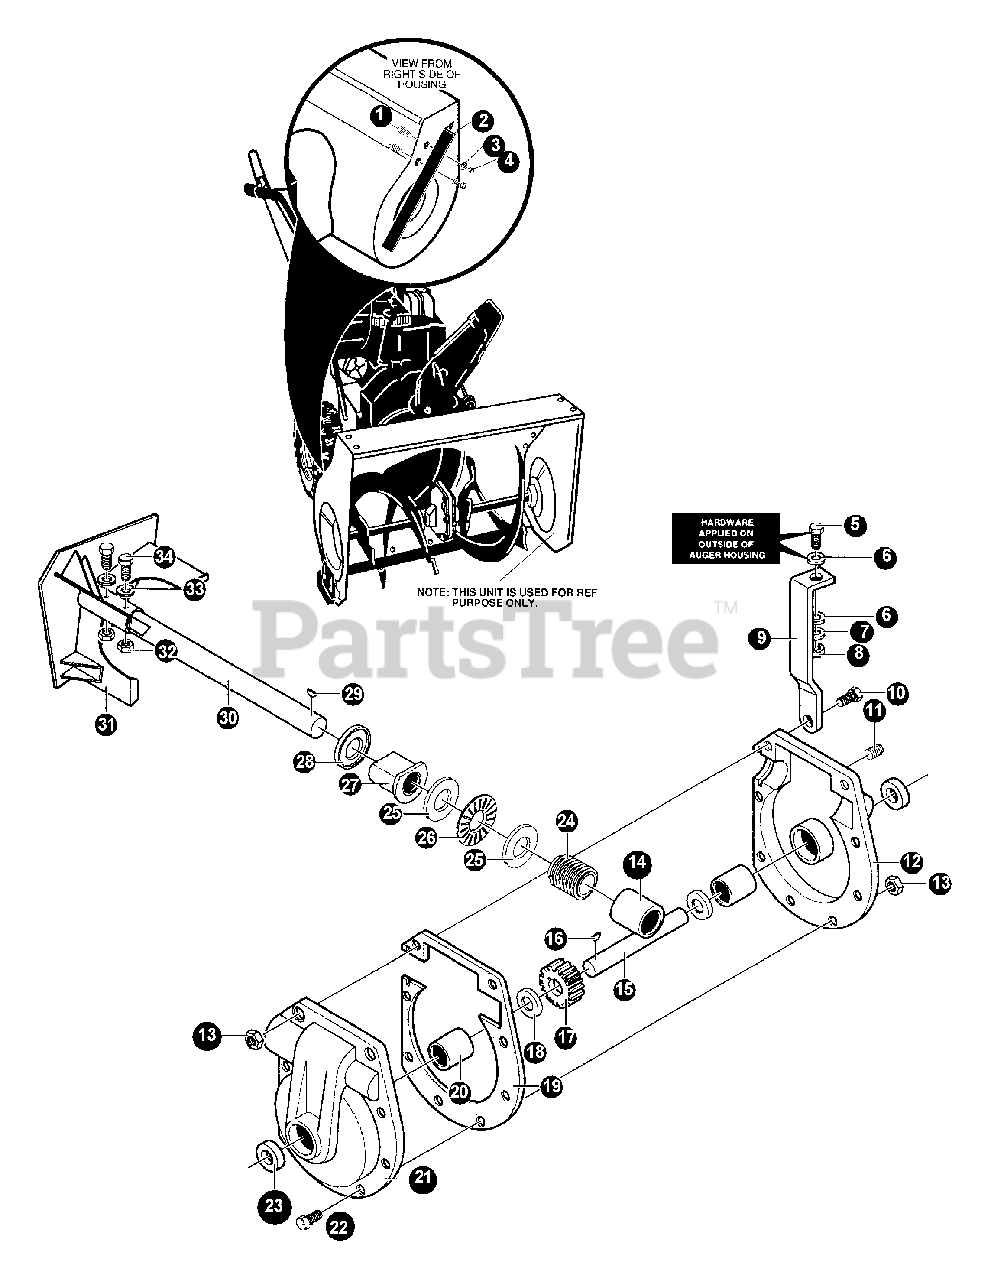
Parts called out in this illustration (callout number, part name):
1	BOLT - 5/16-18 X 3/4"
2	BAR, DRIFT CUTTER
3	LOCKWASHER
4	NUT - 5/16-18
5	SCREW - 5/16-18 X 1-3/4"
6	WASHER
7	LOCKWASHER
8	NUT - 5/16-18
9	BRACE, GEAR BOX
10	SCREW - 5/16-24 X 1-3/4"
11	PLUG
12	CASE, GEAR - LEFT
13	NUT - 5/16-24
14	BEARING, SLEEVE
15	SHAFT, AUGER OUTPUT LF 32"
17	GEAR - WORM
18	WASHER
19	GASKET, GEAR BOX
20	BEARING, SLEEVE
21	CASE, GEAR - RIGHT
22	SCREW - 5/16-24 X 1"
23	SEAL, OIL
24	GEAR - WORM
25	WASHER - .752X1.24X.093
26	BEARING, ROLLER
27	BEARING, FLANGE
28	RING, QUAD
29	KEY, HI-PRO 606 .75DIAX.187WD
30	SHAFT, WORM
31	IMPELLER ASSY
32	NUT - 1/4-20
33	WASHER
34	SCREW - 1/4-20 X 2.25"
